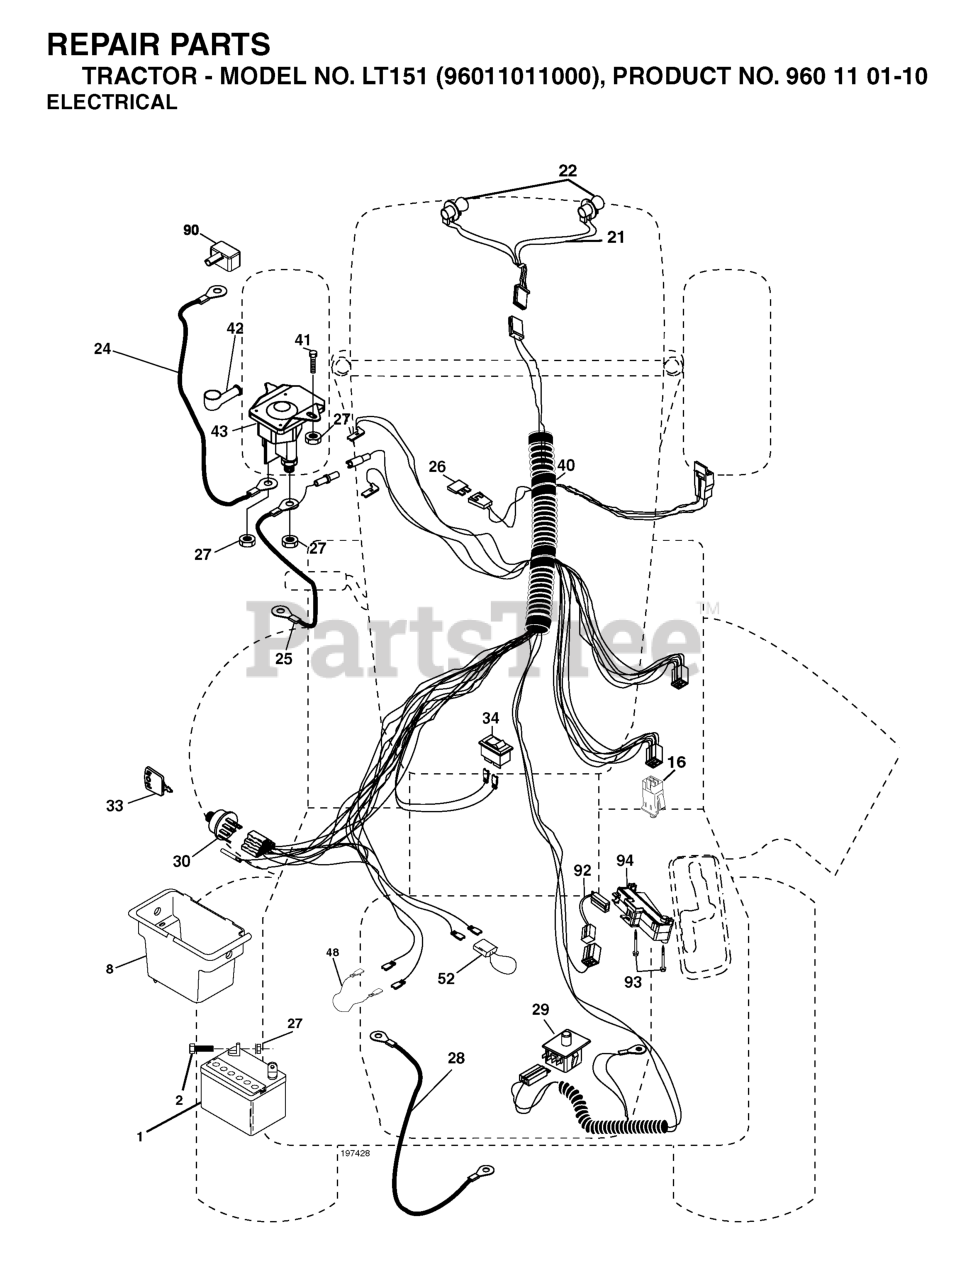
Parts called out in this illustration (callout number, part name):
1	BATTERY 12V .35 AMP
2	BOLT.HEX.1/4.X.3/4.DICHROMATE
8	BOX.BATTERY.FENDER
16	SWITCH INTERLOOK PUSH-IN
21	HARNESS.W/LIGHT SOCKET
24	BATTERY CABLE GT
25	CABLE BATTERY
26	FUSE 20AMP
27	NUT
28	CABLE T
29	SWITCH.SEAT.DP W/RAMPS
30	SWITCH.IGN.DELTA.W.LGH.ROS
33	KEY MLD GEN DELTA
40	HARNESS.IGN.CABLE.REG.
41	BOLT
42	TERMINAL COVER
43	SOLENOID.W/BRASS.PLUNGER
48	ADAPTER.AMMETER
52	WIRE PROTECTION LOOP
90	COVER TERMINAL
92	HARNESS.PIGTAIL.CONSLE
93	SCREW.PLASTITE
94	MODULE.REVERSE.ROS
